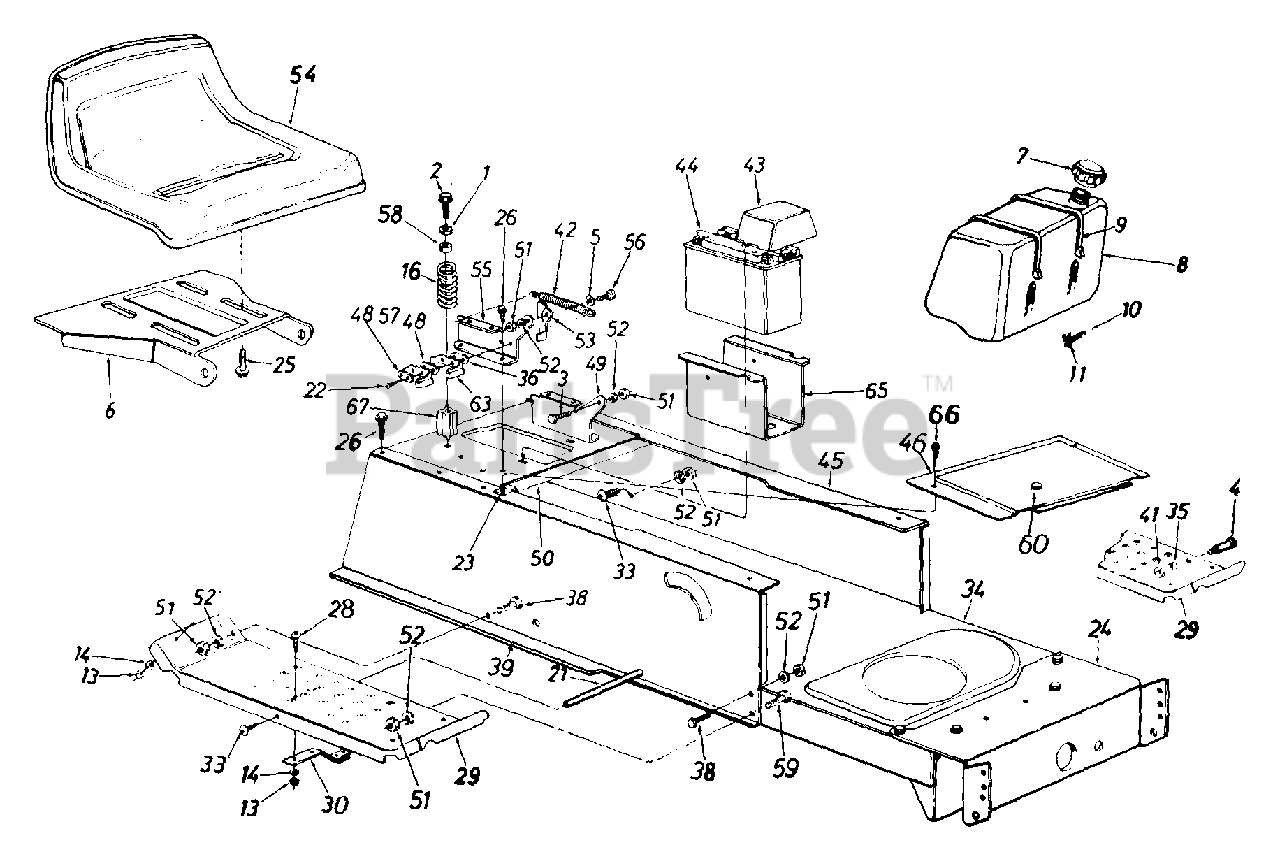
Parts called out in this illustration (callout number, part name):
1	Fl-Wash. .344" I.D. x .875"
2	Hex Wash. Hd. Tap Scr. 5/16-18 x 3.25" Lg.
3	Shld. Bolt .437" Dia. x .162"
4	Shld. Bolt .50" Dia. x .84"
5	Spr-Wash. .445" I.D. x.75
6	Seat Pivot Bracket
7	Fuel Cap
8	Fuel Tank
9	Tie Strap
10	Fuel Line
11	Hose Clamp
13	Hex Nut 1/4-20 Thd.
14	L-Wash. 1/4" I.D.
16	Compression Spring
21	Running Board Rod
22	Hex Wash. Hd. AB-Tap Scr. #8 x .50" Lg.
23	Speed Nut #10Z
24	Front Pivot Brkt.
25	Hex Tap Scr. 3/8-16 x .75"
26	Hex Wash. Hd. AB-Tap Scr. 5/16 x .75" Lg.
28	Carriage Bolt 1/4-20 x .62"
29	Running Board (R.H. 8 L.H,)
30	Blade Brake Ass'y.
33	Truss Mach. Scr. 5/16-18 x .75" Lg."
34	Lower Frame
35	L-Wash. 3/8" I.D.
36	Insulator Boss Plate
38	Hex Bolt 5/16-18 x .75" Lg.
39	Upper Frame - R.H.
41	Hex Nut 3/8-16 Thd.
42	Extension Spring 5.31" Lg.
43	Battery Cover
44	12-V Battery (275 Cold Crank Amps)
45	Upper Frame - L.H.
46	Shift Cover
48	Insulator Plate
52	L-Wash. 5/16" I.D.
53	Seat Lift Brkt.
54	Seat 8-7/8" High
56	Shld. Bolt .437" Dia. x .268"
57	Spring Switch
58	Bushing
59	Hex Wash. TT-Tap Scr. 5/16-18 x 7/8" Lg.
60	Snap Bushing
63	Safety Switch (Seat)
65	Battery Tray
66	Truss Mach. B-Tap Scr. #10 x .5" Lg.
67	Spring Spacer
